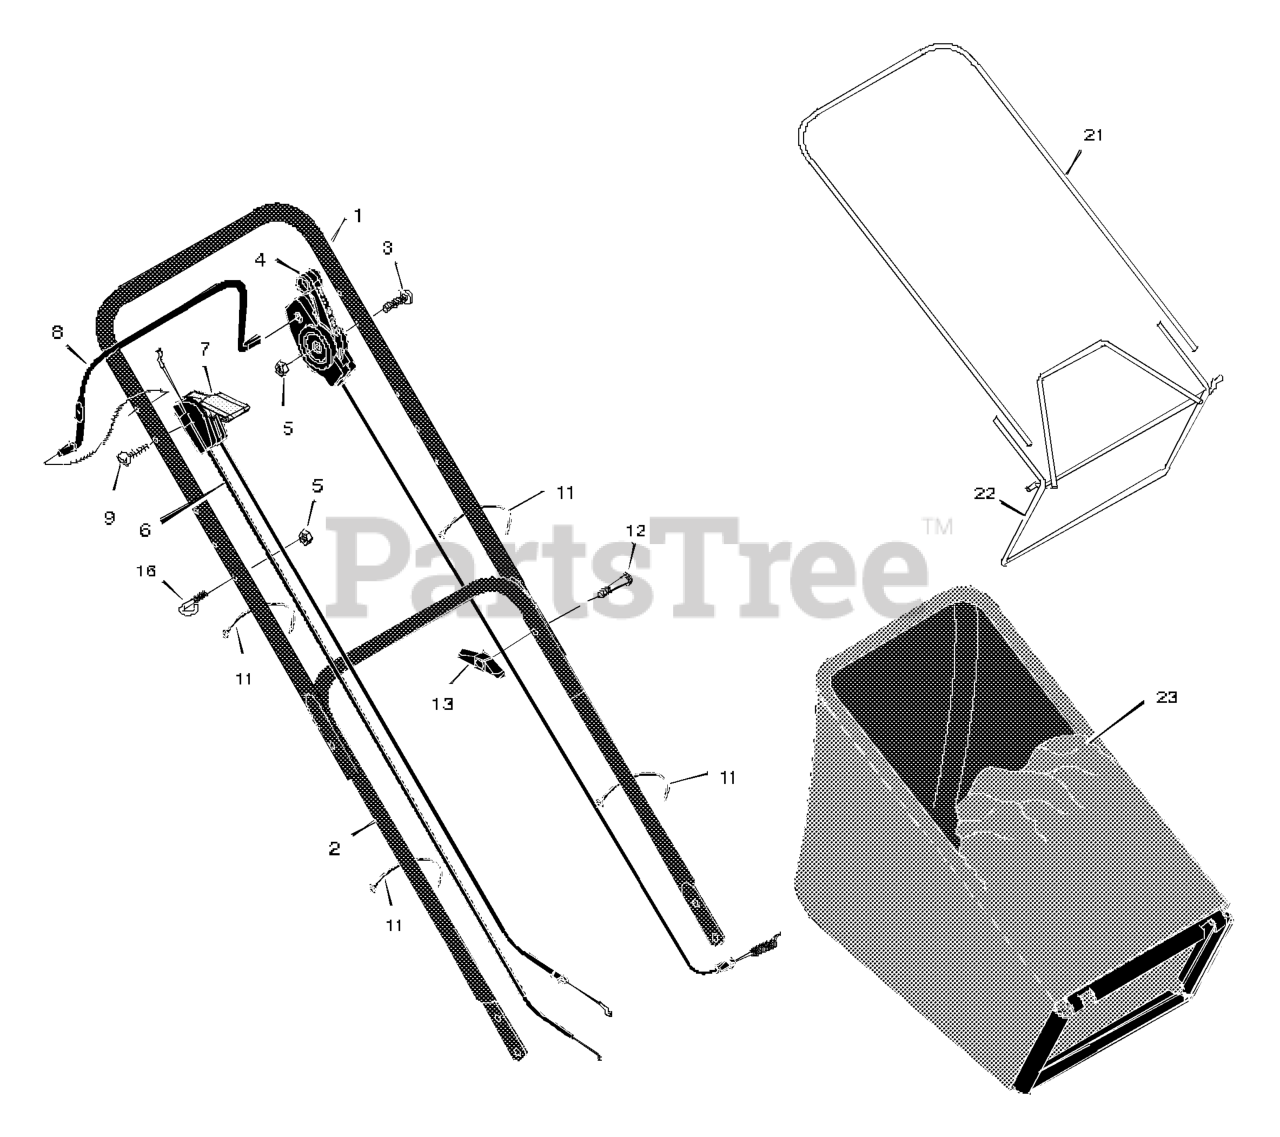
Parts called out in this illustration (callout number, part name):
1	Handle, Upper (Black)
2	Handle, Lower (Black)
4	Control, Drive
5	Locknut
6	Cable, Stop
7	Throttle Control
8	Lever, Stop
11	Fastener, Cable
13	Knob
16	GUIDE, ROPE
21	Frame, Top
22	Frame Assembly
23	Bag, Cloth
